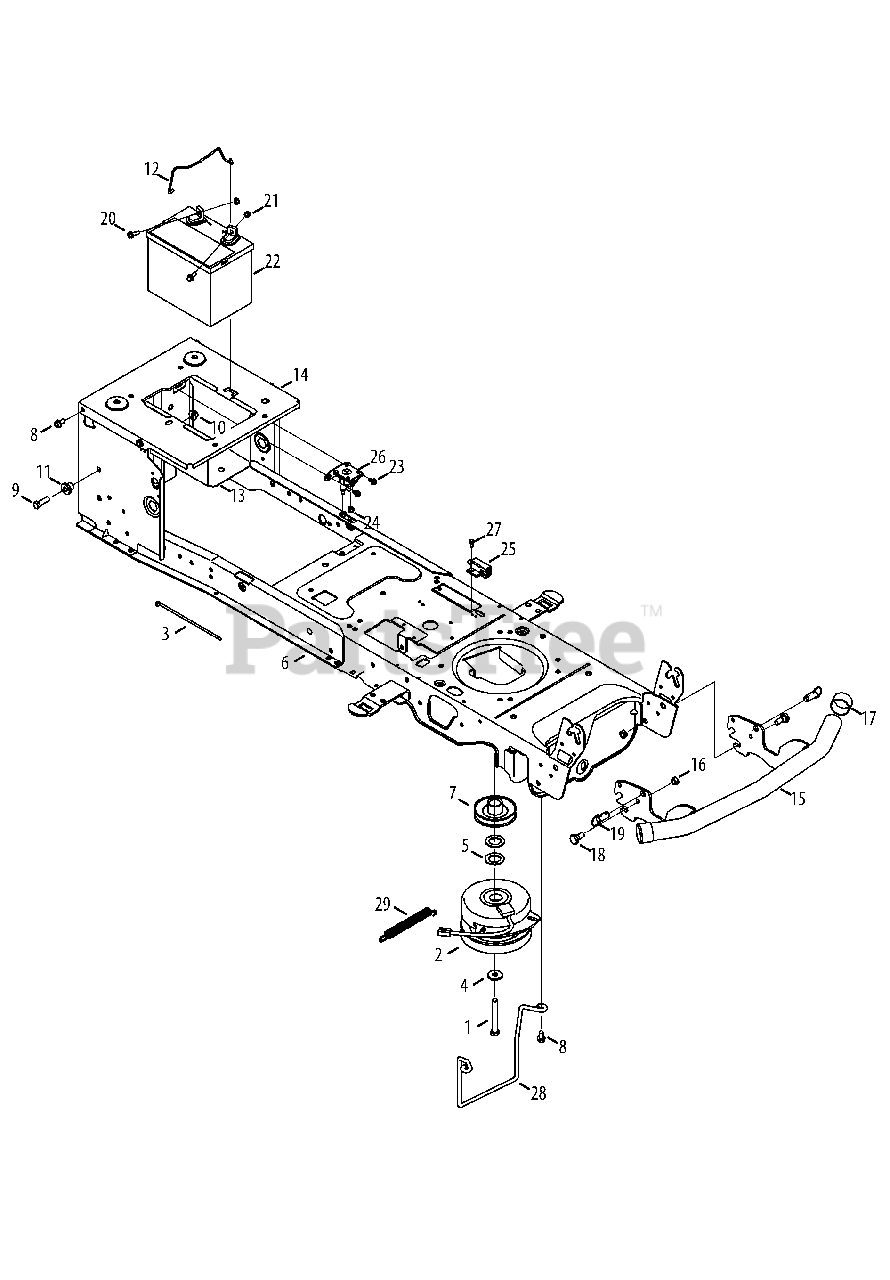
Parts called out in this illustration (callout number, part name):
1	Hex Head Screw, 7/16-20:3.50
2	Electric PTO Clutch
2	Clutch Wire Jumper
3	Cable Tie, 3/16 x .05 x 7.4
4	Washer, Flat, .450 x 1.25 x .164
5	Flat Washer, 1.031 x 1.620 x .095
6	Frame
7	Electric PTO Engine Pulley
8	Taptite Screw, 5/16-18:.750
9	Hex Head Screw, 3/8-16:1.25
10	Flangelock Nut, 3/8-16
11	Shoulder Spacer, .38 x 1.0 x .70
12	Battery Holder Rod
14	Seat Frame Bracket
16	Hex Lock Nut, 3/8-16
17	Bumper Cap
18	Shoulder Bolt, .496 x .336
19	Quick Release Pin
20	Hex Head Flange, 1/4-20:.75
21	Sems Nut, 1/4-20
23	Taptite Screw, 1/4-20:0.375
24	Flangelock Nut, 1/4-20
25	Interlock Switch
26	Solenoid, 12 V
27	Shoulder Screw, #10-32:.500
28	Belt Keeper Rod
29	Spring, Extn, .56 Dia X 5.52
